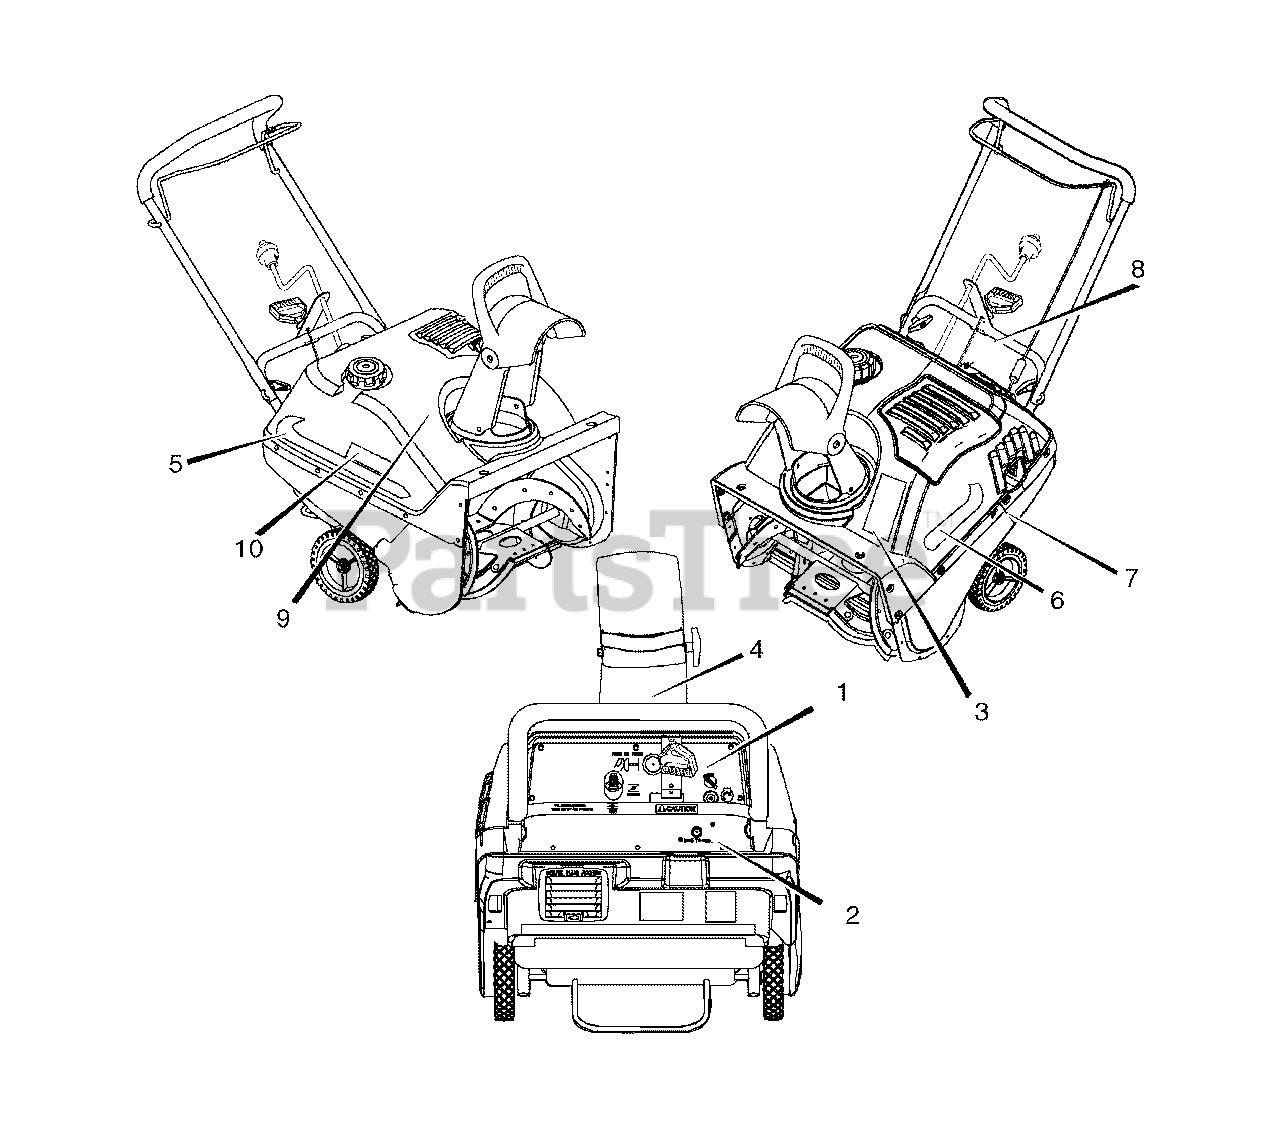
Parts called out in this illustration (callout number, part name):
1	DECAL, Control Panel English 22"
2	DECAL, Electric Start
3	DECAL, Danger Auger
4	DECAL, Danger Chute
5	DECAL, Simplicity R.H.
6	DECAL, Simplicity L.H.
7	DECAL, Hot Muffler
8	DECAL, Auger Control
9	DECAL, Briggs & Stratton
10	DECAL, 5022 R.H.
